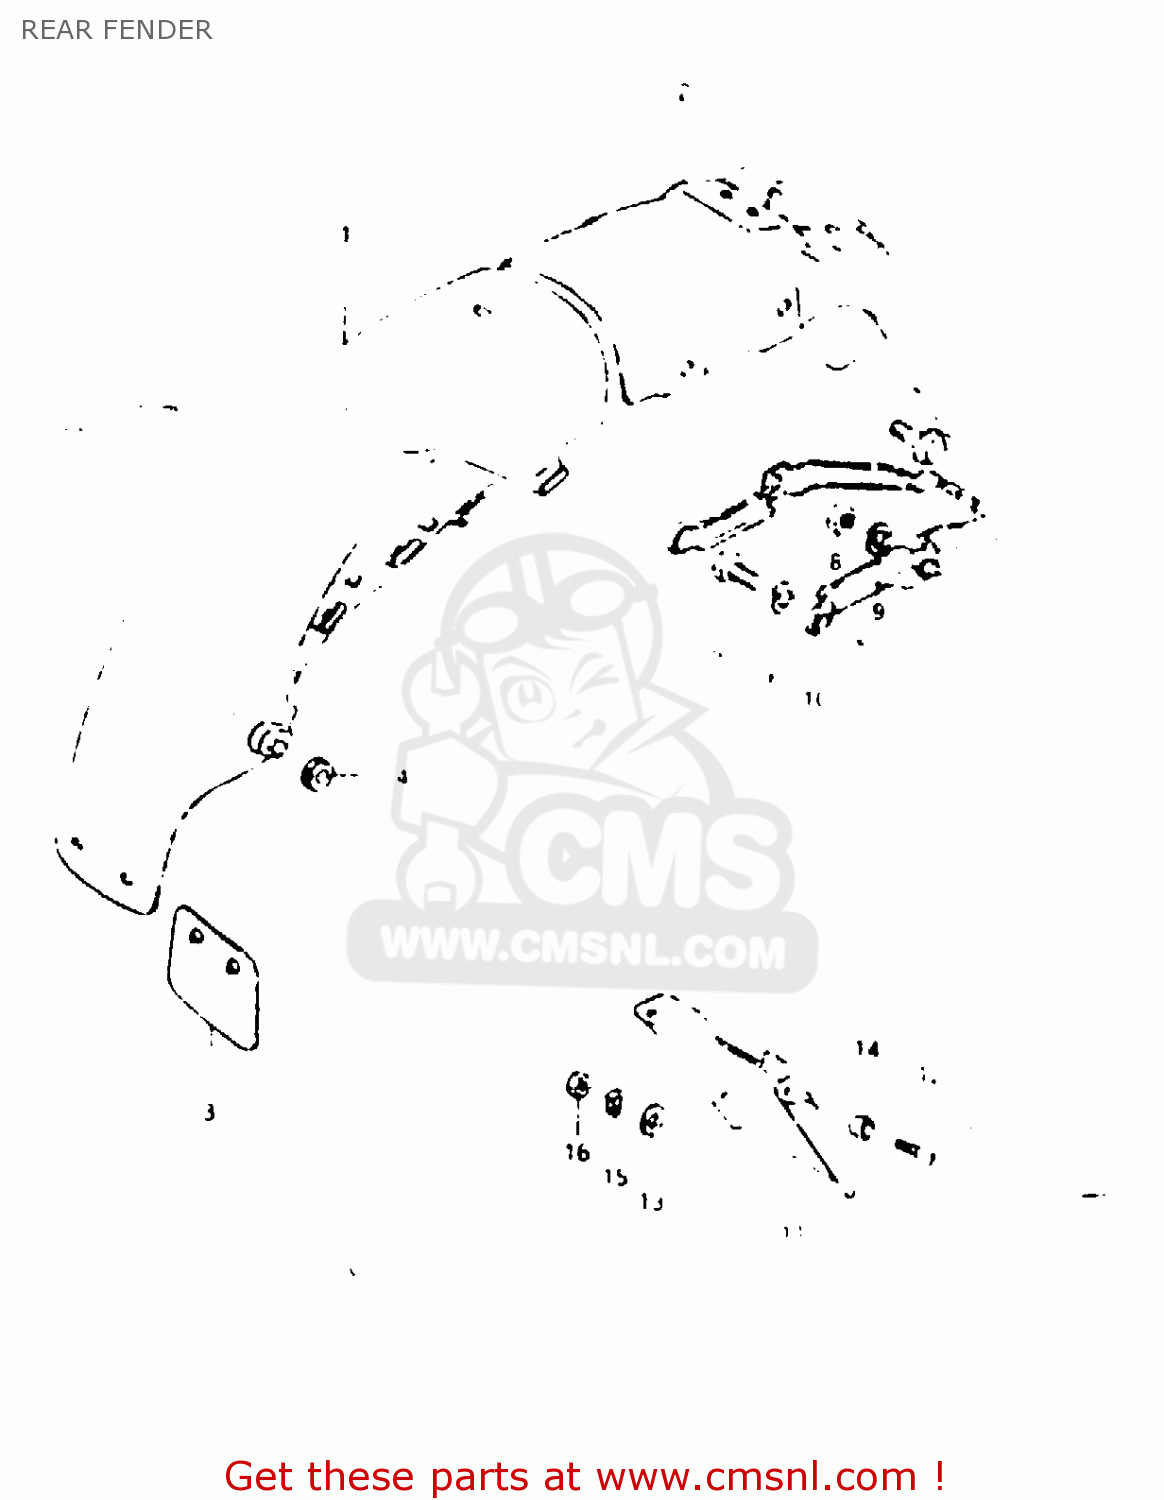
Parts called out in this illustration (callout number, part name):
1	FENDER,REAR
2	BODY,RR FENDER RR
3	GUIDE,RR FENDER MUD
4	CUSHION
5	BOLT, UPPER
6	LOCK WASHER
7	BOLT
8	NUT
9	LOCK WASHER
10	REINFORCEMENT,RR FENDER
11	EXTENSION
12	SCREW (6X15)
14	SPACER(6.2X8.3X5.7)
15	LOCK WASHER
16	NUT
